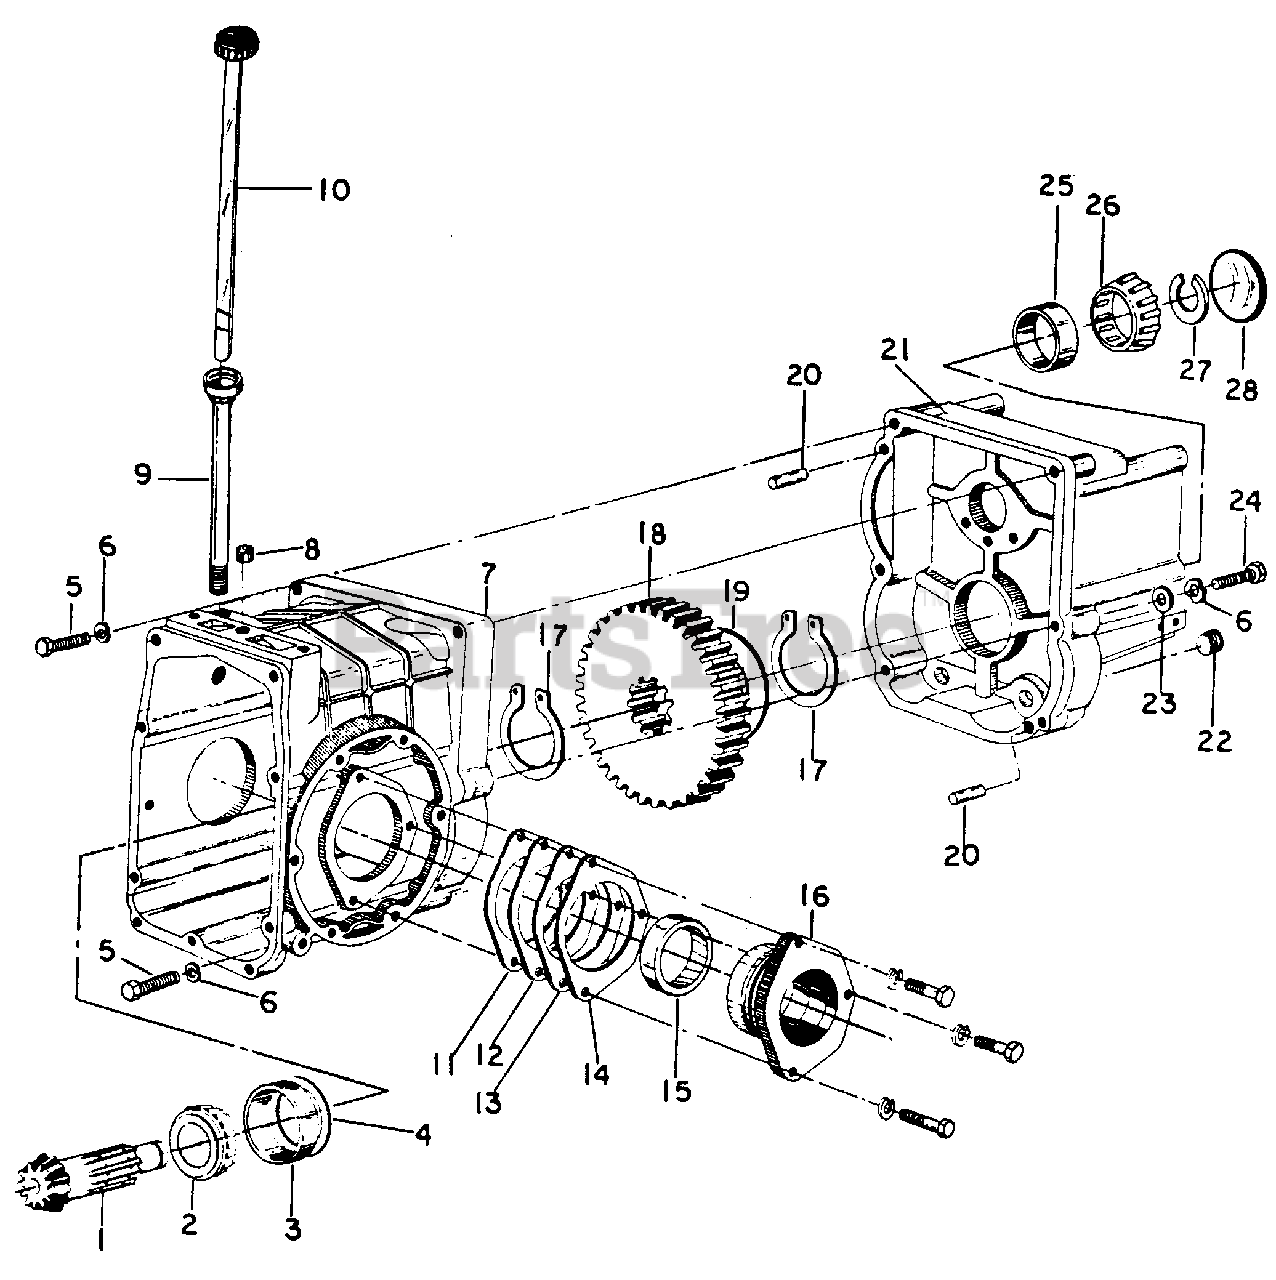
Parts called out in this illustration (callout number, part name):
1	Shaft, Bevel Pinion
2	Bearing Assy, Pinion Shaft Rear Cone
3	Bearing, Pinion Shaft Rear Cup
4	Shim, Rear Bearing Cup, .004
5	Bolt, 7/16 X 1-3/4 Type 5
6	Washer, 7/16 ID Belleville
7	Housing Assy, Rear
8	Plug, Breather
9	Tube, Dipstick
10	Dipstick Assy
11	Shim, Bearing Retainer, .004
12	Shim, Bearing Retainer, .007
13	Shim, Bearing Retainer, .0149
14	Shim, Bearing Retainer, .0299
15	Bearing, Cup
16	Retainer, Bearing
17	Ring, Retaining
18	Gear, Constant Mesh -66T
19	Spacer, Pinion Shaft Gear
20	Pin, 3/8 X 5/8 Dowel
21	Housing, Adapter
22	Plug, 1/2-14 Pln H/Hd Pipe
23	Washer, .438 X .875 X .064
24	Bolt, 7/16 X 2-1/2 Type 5
25	Bearing, Pinion Shaft Front Cup
26	Bearing, Pinion Shaft Front Cone
27	Ring, Front Bearing Retainer, .125
28	Plug, 2-1/8 Pln Expansion
